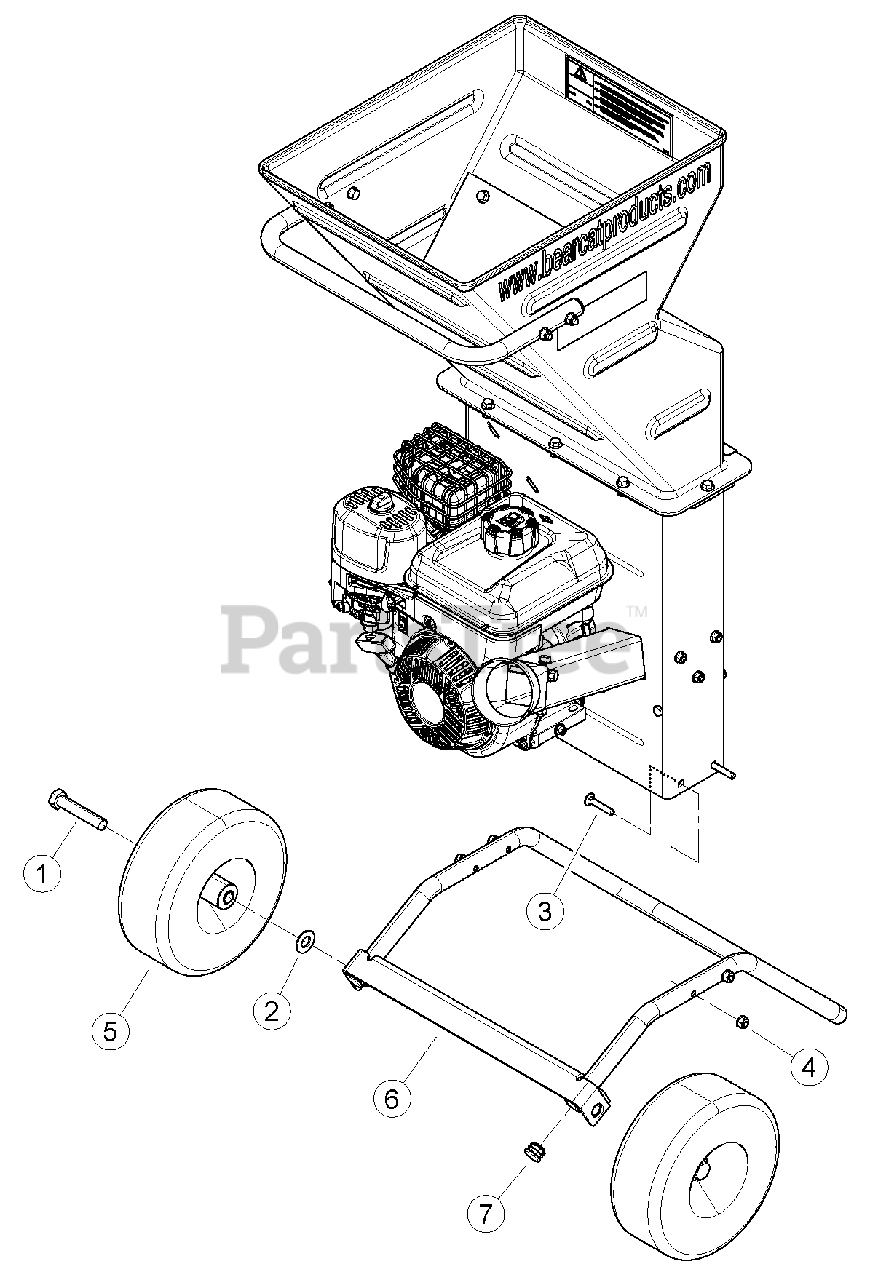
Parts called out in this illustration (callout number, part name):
1	BOLT, 5/8 X 3-1/4 HEX GR5 ZP
2	WASHER, 5/8 SAE FLAT
3	BOLT, 5/16 X 1-3/4 GR5 CRG ZP
4	NUT, 5/16-18 NYLOCK FLANGE
5	ASSEMBLY, 410/350-4 FLAT-FREE WHEEL
6	ASSEMBLY, SC2163 STAND
7	PLUG, 1" ROUND RIBBED
